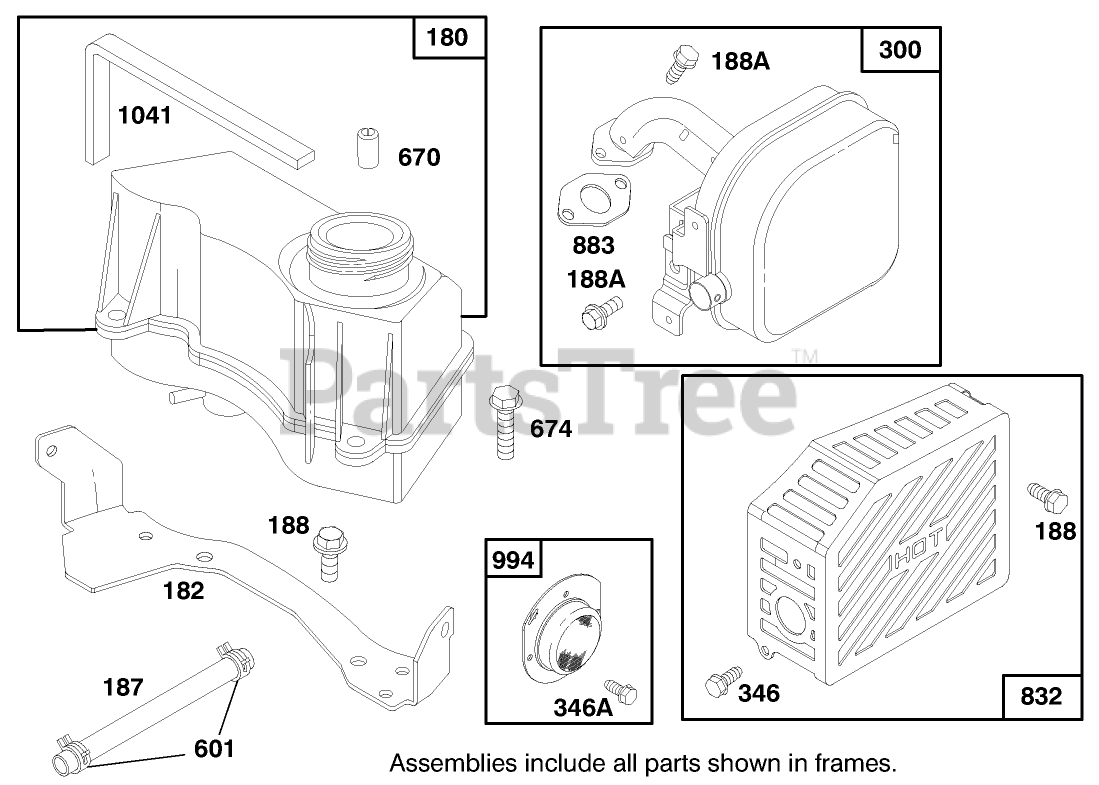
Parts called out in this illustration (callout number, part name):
180	TANK ASSY - FUEL
187	BRIGGS 296004
188	SCREW - SEM
188A	SCREW - HEX HEAD
300	MUFFLER - EXHAUST
346	SCREW - SELF-TAPPING
346A	SCREW - SELF-TAPPING
670	SPACER
674	SCREW - HEX HEAD
